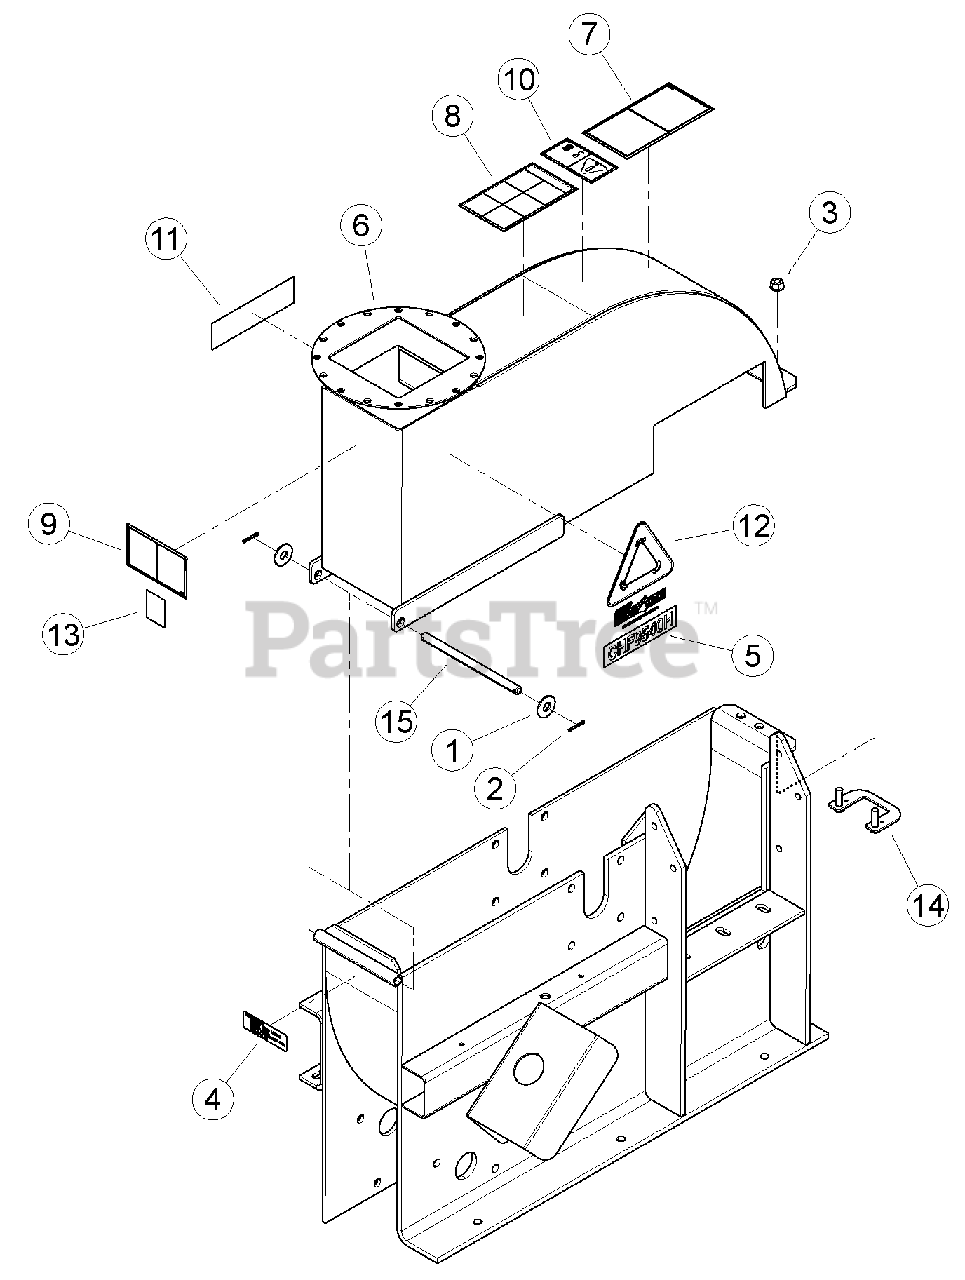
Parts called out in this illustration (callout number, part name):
1	WASHER, 1/2" FLAT ZP
2	PIN, 1/8 X 1.00 ZP COTTER
3	NUT, 3/8-16 NYLOCK FLANGE
4	DECAL, ATLANTIC BRIDGE LTD INFO (CE COMPLIANT ONLY)
5	DECAL, MODEL CHF9540H
6	ASSEMBLY, CHIPPER COVER W/ DECALS
7	DECAL, KNIFE ACCESS ISO
8	DECAL, OPERATING INSTRUCTIONS ISO
9	DECAL, DISCHARGE ISO
10	DECAL, MAINTENANCE ISO
11	DECAL, ECHO BEARCAT 6.82 X 1.90
12	DECAL, CHIP IT
13	DECAL, ECHO BEARCAT QR CODE
14	WELDMENT, CHIPPER HOUSING ACCESS
15	SHAFT, CHIPPER TOP PIVOT
